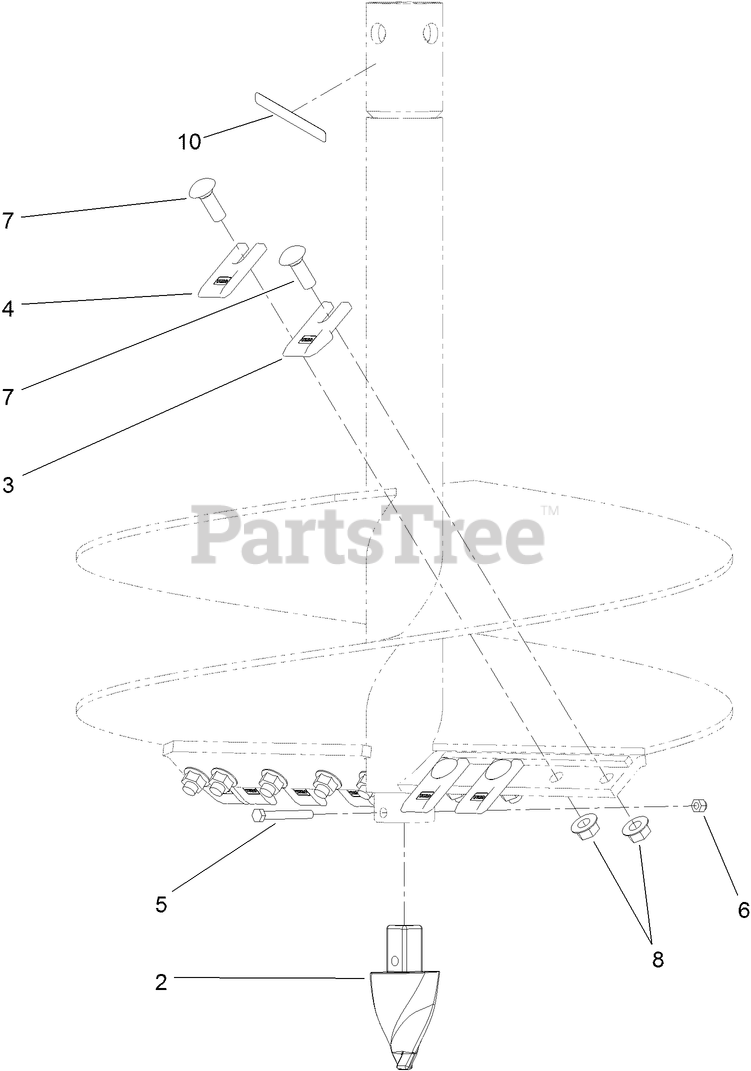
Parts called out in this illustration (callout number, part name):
2	PILOT-AUGER
3	TOOTH-OUTER
4	TOOTH-INNER
5	SCREW-HH
6	NUT-HF
7	SCREW-CARR
8	NUT-FLANGE
10	DECAL-WARNING
